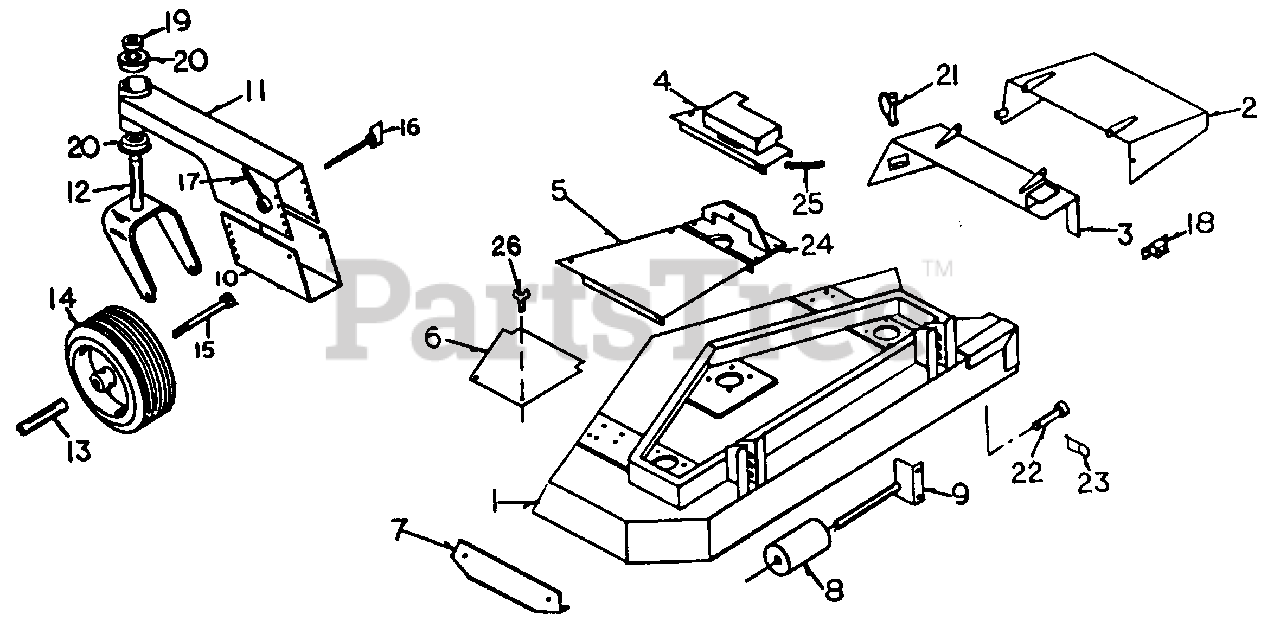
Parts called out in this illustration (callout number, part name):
1	Deck
3	Foot Guard Mount
8	Anti-scalp Roller
9	Shaft & Bracket
10	Gauge Wheel Mount Bracket
11	Gauge Wheel Mount
12	Fork
14	Cauge Wheel Assembly
15	Hex Bolt, 1/4-20 x 4 1/2", GR5
18	10 Amp Circuit Breaker
19	Set Collar, l"
23	Hair Pin Cotter
24	Deck Mount
26	Thumb Screw, 1/4-20 x 1/2"
